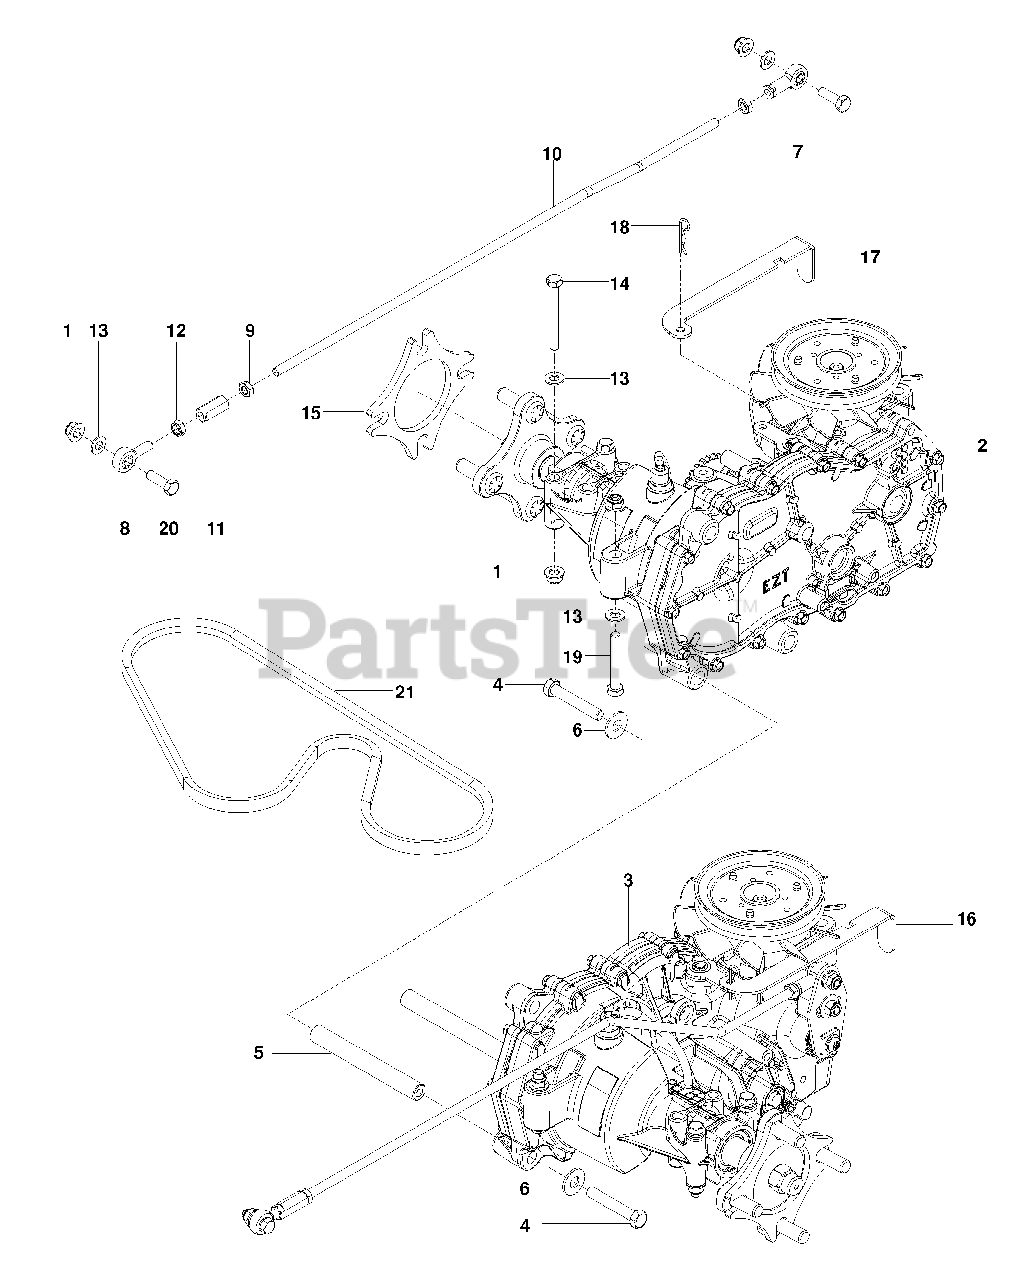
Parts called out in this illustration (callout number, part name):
1	NUT 5/16-18 FLANGE NYLOC
2	HYDRO, RH
4	HCS 3/8-16 x 2 1/4
5	SPACER, HYDRO
6	WASHER 3/8 FLT STD
7	ROD END, RH
8	ROD END, MALE LH
9	NUT 5/16-24 HEX JAM
10	ROD, CONTROL
11	ROD END COUPLER
12	NUT 5/16-24 HEX JAM LH
13	WASHER 5/16 SAE FLT
14	HCS 5/16-18 x 2 3/4
15	SPACER, WHEEL
16	RELEASE HANDLE, LH
17	RELEASE HANDLE, RH
18	HAIRPIN COTTER
19	HCS 5/16-18 x 2 1/4
20	HCS 5/16-18 x 1
